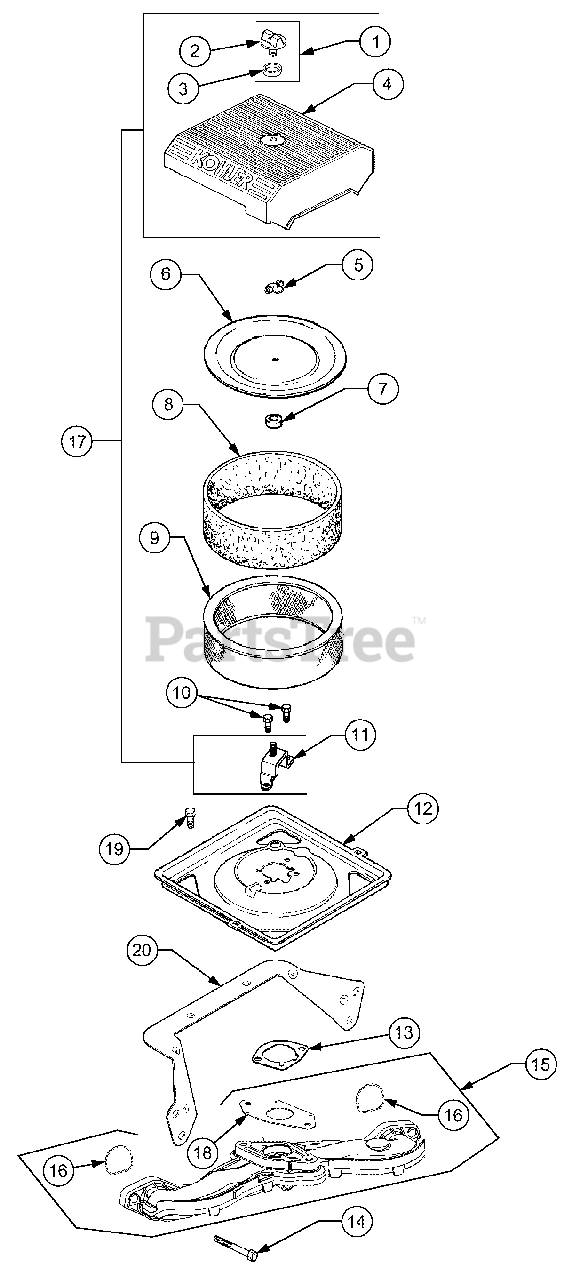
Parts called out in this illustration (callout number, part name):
1	Kit, Knob w/Seal
3	Seal, Air Cleaner Cover Knob
4	Cover, Air Cleaner
6	Cover, Inner Air Cleaner
7	Seal, Inner Air Cleaner
8	Precleaner, Element
9	Element, Air Cleaner
10	Screw, Hex Flange, M6 x 1.0 x 16
11	Bracket, Air Cleaner Base
12	Base, Air Cleaner
13	Gasket, Air Cleaner Base
14	Screw, Hex Flange, M6 x 1.0 x 40
15	Manifold, Intake
16	O-Ring, Intake Manifold
17	Kit, Air Cleaner Cover
18	Gasket, Carburetor
19	Screw, Hex Flng, M5 x 0.8 x 10
20	Bracket, Air Cleaner Base
